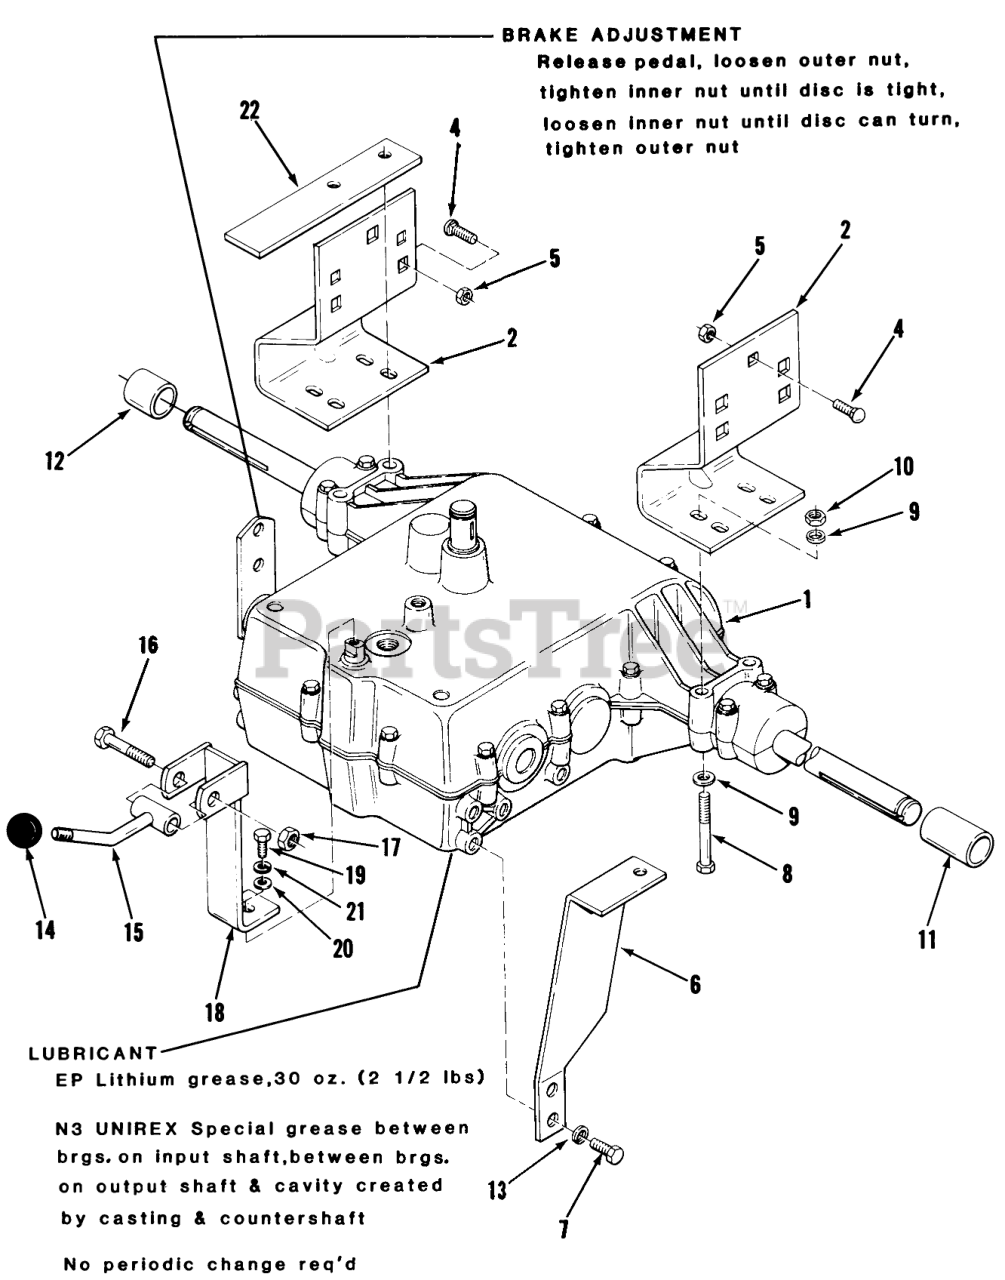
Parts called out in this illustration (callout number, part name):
1	Transmission-Peerless Model 801-002
1	Transmission-Peerless Model 822
2	BRKT-TRANS MOUNT R
4	CARRIAGE BOLT -4
5	Nut
6	TORQUE STRAP
7	Screw
8	HHCS
9	WASHER 5/16 SAE
10	Nut
11	SPACER-AXLE LH
12	SPACER-AXLE RH
13	Lockwasher
15	ASSY-UPPER SHIFT ROD
16	Bolt
17	Nut
18	ASSY LEVER R
19	Bolt 1/4-28 X 7/8
20	WASHER
21	Washer
22	Brake Stop Bar
